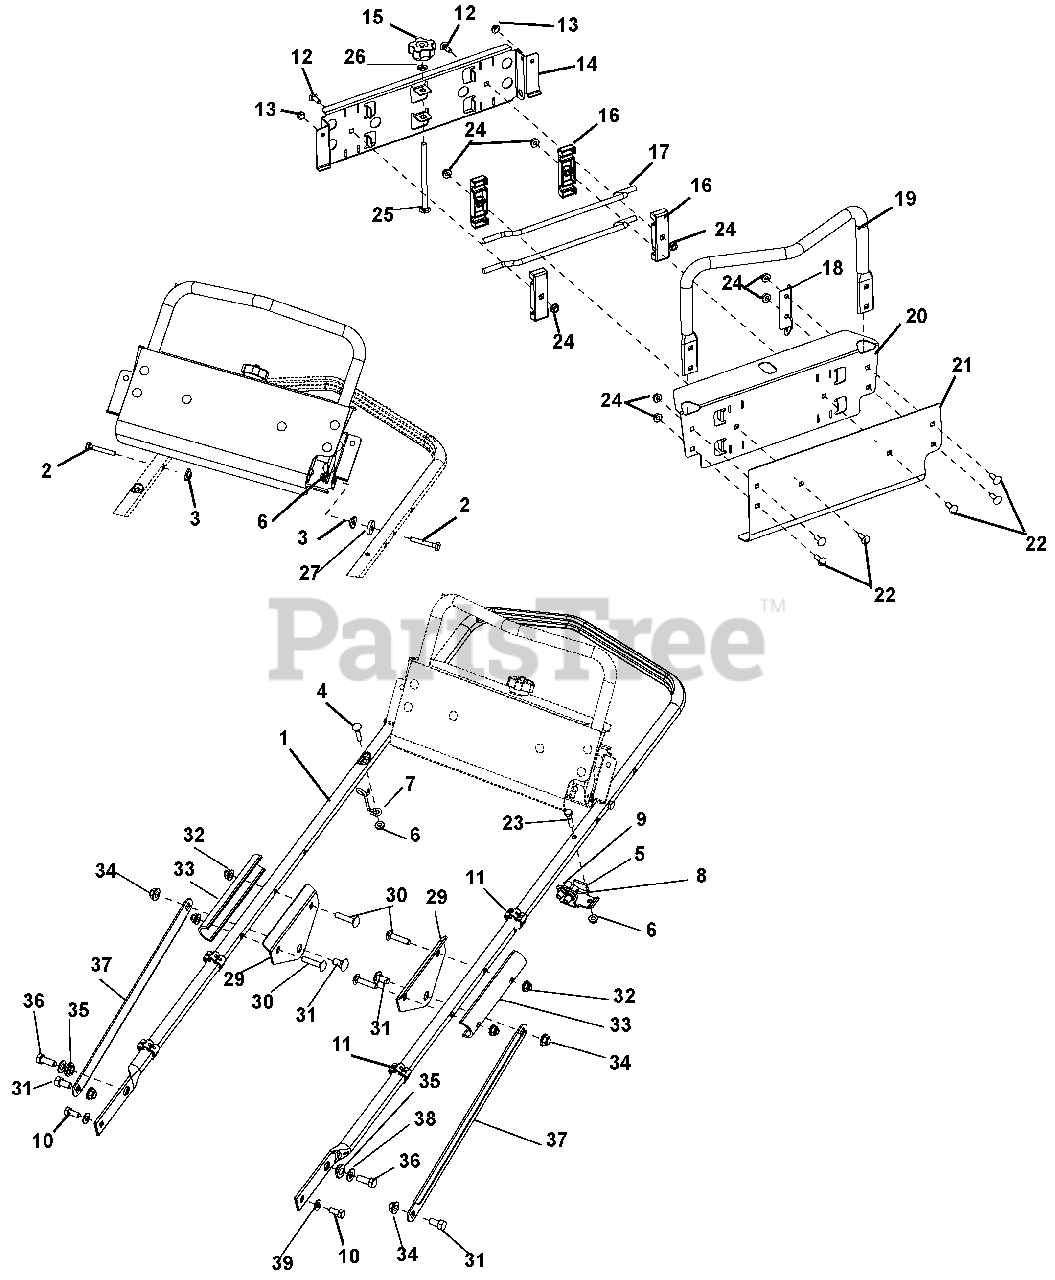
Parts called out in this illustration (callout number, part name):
1	HANDLEBAR,PRO 21
2	@BLT-HEX .25-20X1.75 GR5 YWZC
3	BSHG-FLG .265X.437X.250X.750
4	BLT-RDHDXLSQNK.25-20X1.25 G5ZC
5	BKT,CABLE ANCHOR
6	@NUT-LK-TOP-FLG .25-20 YWZC
7	GUIDE - PULLCORD
8	CABLE,OPC (DLX) KAWASAKI
9	CABLE-DRIVE
10	@BLT-HEX .31-18X.75 GR5 YWZC
11	CONDUIT CLIP
12	@BLT-RDHDSQNK .25-20X1.00 G5YZ
14	PLATE,HINGE
15	KNOB-CLAMPING, .312-18 NYLOC
16	CLAMP,4-BAR
17	ROD,4-BAR
18	CABLE ANCHOR
19	BAIL .750 TUBE
20	COVER,OP CONTROL
21	COVER,SHEETMETAL
22	@BLT-RDHDSQNK .25-20X1.00 G5YZ
23	@BLT-HEX .25-20X1.25 GR5 YWZC
24	@NUT-SPNLK-FLG .25-20 YWZC
25	BLT-RDHDSQNKFTH.31-18X5 GR5YZC
26	NUT-PUSH .312
27	WSHR-FL-STL .328X.87X.179 YWZC
28	@NUT-LK-CTR .25-20 YWZC
29	PLATE,HANDLEBAR
30	@BLT-RDHDSQNK .31-18X1.50 G5YZ
31	@BLT-HEX .38-16X.75 GR5 YWZC
32	@NUT-LK-NYL-FLG .31-18 YWZC
33	SERVICE BAR BRACE
34	@NUT-LK-NYL-FLG .38-16 YWZC
35	BSHG-FLG .406X.88X.270X.140
36	@BLT-HEX .38-16X1.00 GR5 YWZC
37	STRAP,HANDLEBAR
38	@WSHR-FL-STL.406X.812X.065 YWZ
39	@WSHR-FL-STL.344X.688X.065YWZC
